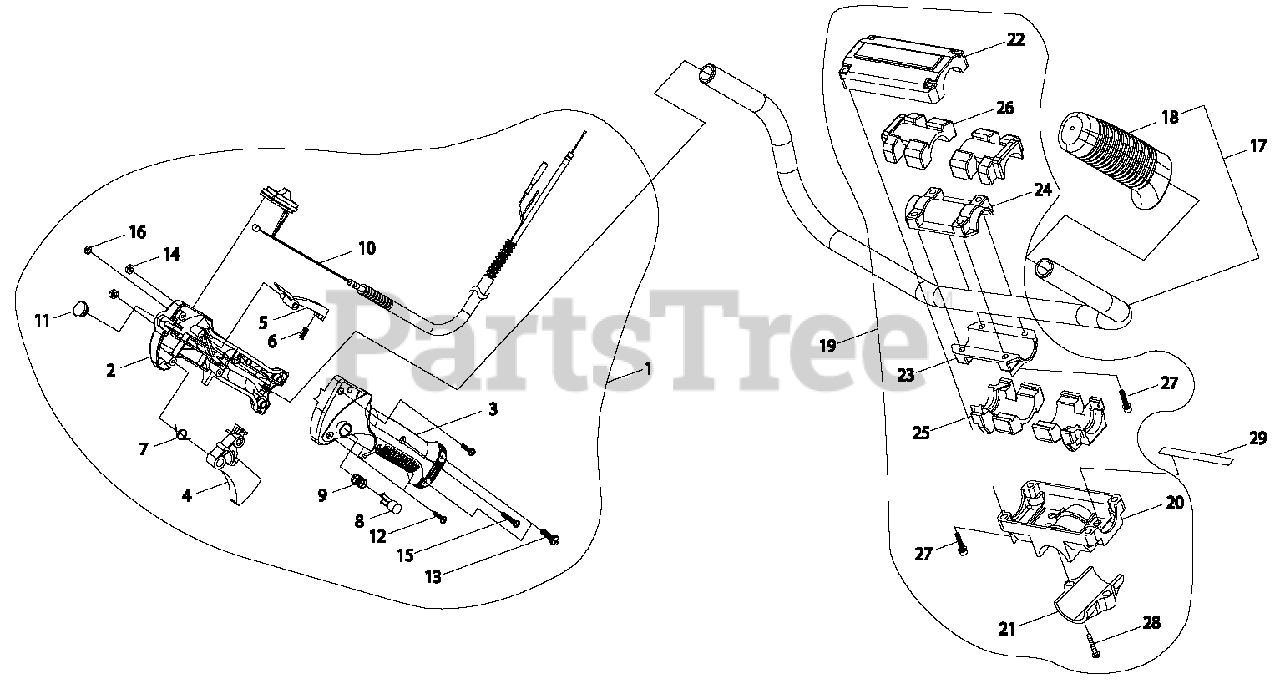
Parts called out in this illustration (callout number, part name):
1	TRIGGER, THROTTLE
2	HANDLE, CONTROL - RIGHT
3	HANDLE, CONTROL - LEFT
4	TRIGGER, THROTTLE
5	LEVER, TRIGGER LOCKOUT
6	SPRING
7	SPRING, TRIGGER
8	LOCK, THROTTLE
9	SPRING
10	CONTROL CABLE ASSY
11	PLUG
12	SCREW - 4X16 -- TAPPING
13	SCREW - 4X16 -- TAPPING
14	NUT - 5
15	SCREW - 4X23
16	NUT - 4
17	HANDLE ASSY
18	GRIP
19	HANDLE BRACKET KIT
20	BRACKET, HANDLE
21	SPACER
22	CAP - UPPER
23	CLAMP - LOWER
24	CLAMP - UPPER
25	CUSHION - LOWER
26	CUSHION - UPPER
27	SCREW - 5X25
28	SCREW - 6X25
29	LEAD - GROUND
